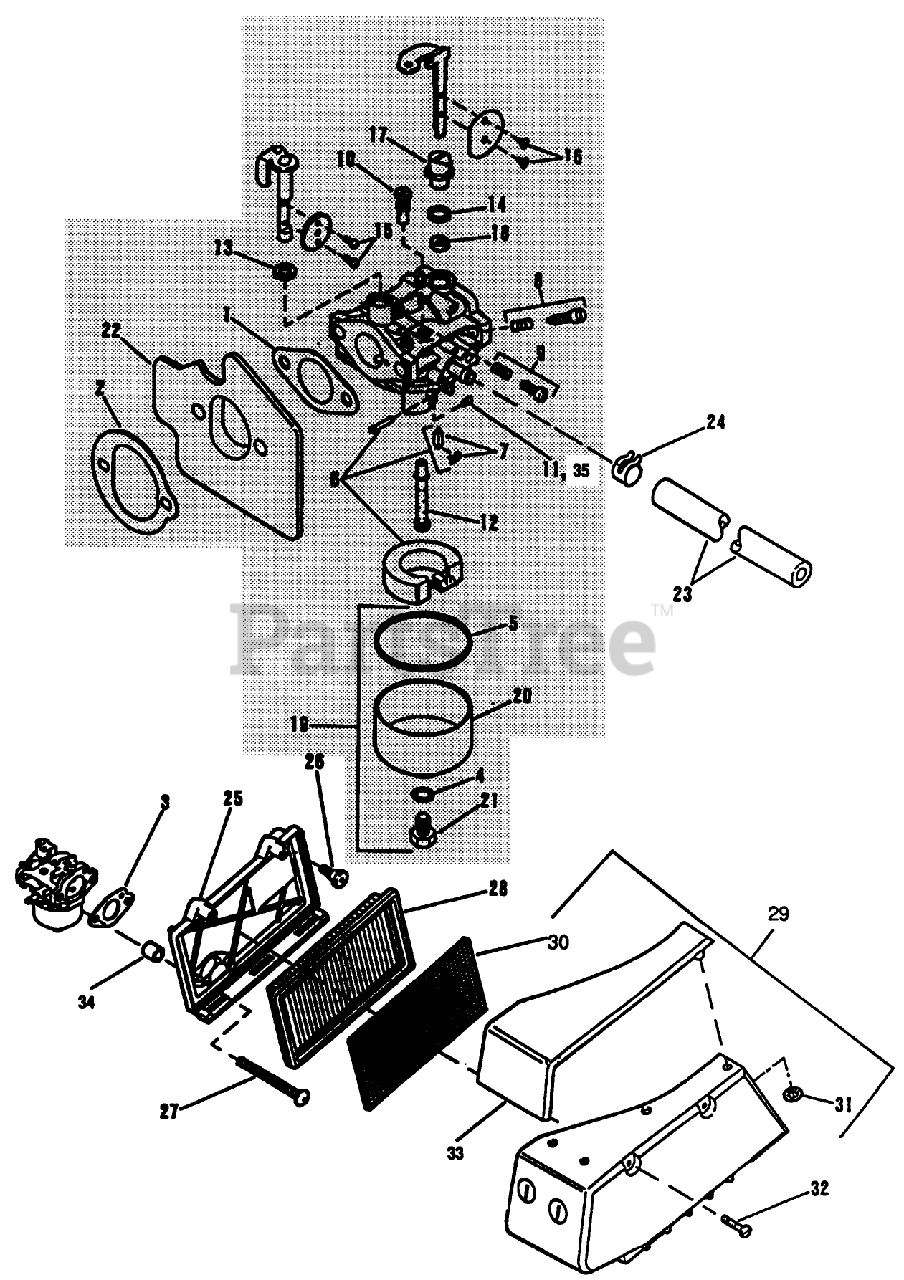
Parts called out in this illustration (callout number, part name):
1	GASKET SM
2	GASKET SM
3	GASKET-FIL SM
4	GASKET-BOWL RET S
5	GASKET-FUELBOWL S
7	NEEDLE & CLIP S
10	PILOT JET
11	CARB JET
14	SEAL CHOKE SHAFT
16	SCREW CHOKE VALVE
21	SCREW,BOWL RET S
23	GAS LINE SM
24	HOSE CLAMP SM
28	ELEMENT-AIR SM
29	AIR FILTER COVER
31	NUT-PUSH
35	MAIN JET
